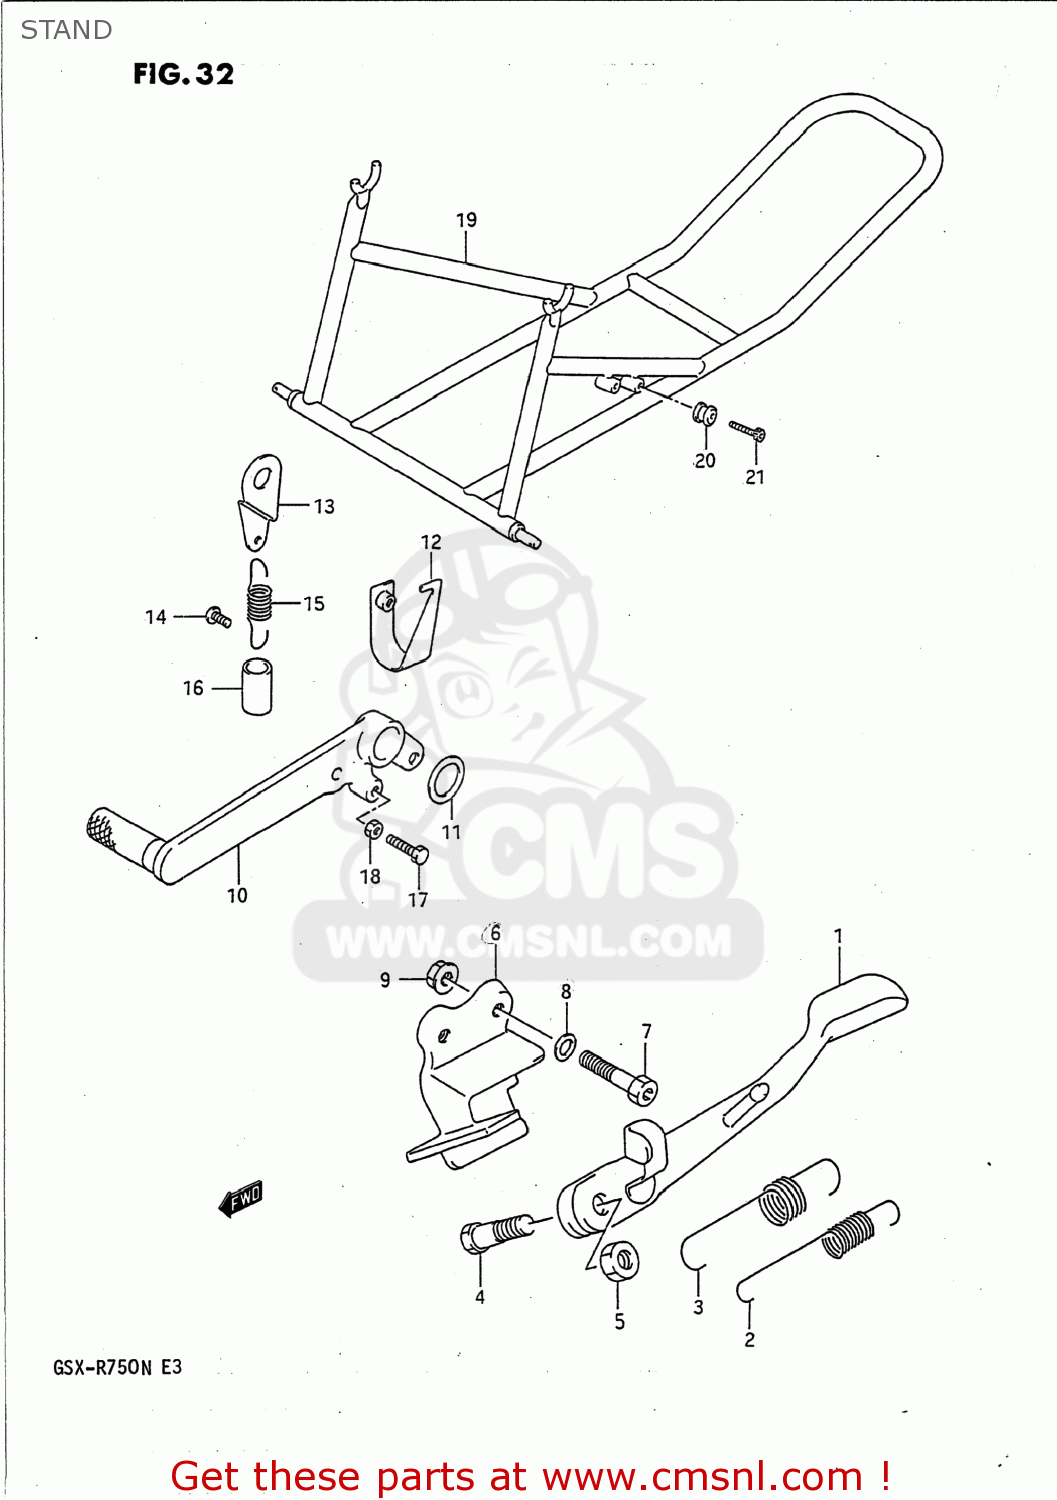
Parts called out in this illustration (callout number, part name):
1	STAND,PROP
2	SPRING
3	SPRING
4	BOLT(10X38)
5	NUT
6	BRACKET COMP,PROP STAND
7	BOLT, FRONT RH
8	WASHER
9	NUT
10	PEDAL,BRAKE
11	WASHER(18X24X1)
12	PLATE,BRAKE SPRING,FRONT
13	BRACKET,STOP SWITCH SPRING
14	SCREW(6X12)
15	SPRING
16	TUBE,BRAKE SPRING GUIDE
17	BOLT
18	NUT 5MM
19	STAND ASSEMBLY,REAR
20	HOLDER,STAND
21	BOLT, REAR (8X30)
